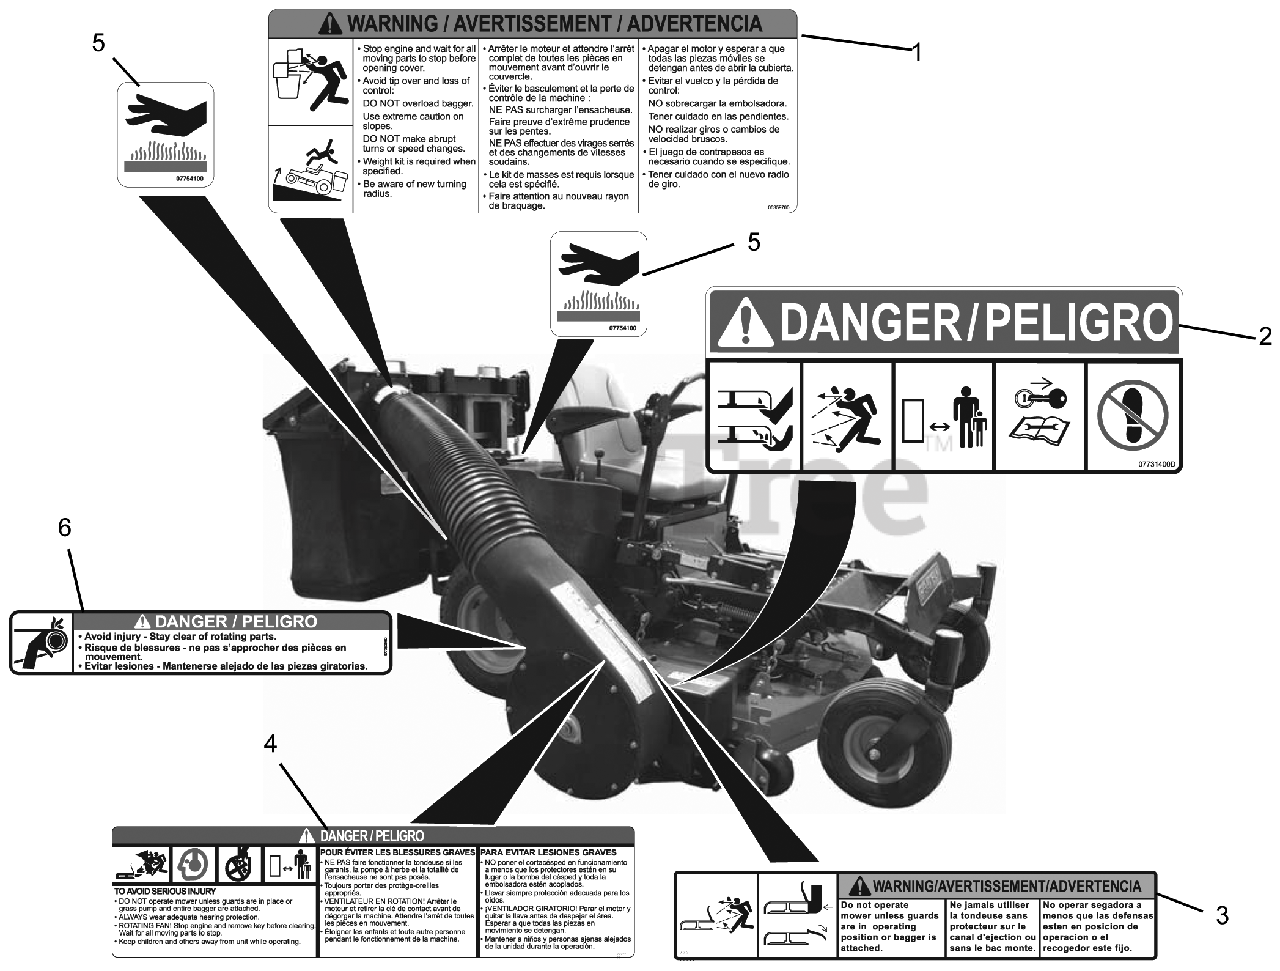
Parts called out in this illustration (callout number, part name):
1	DECAL, BAGGER COVER
2	DECAL, MOWER PAN DANGER
3	DECAL, WARNING
4	DECAL-CAUTION, GRASS PUMP
5	DECAL, HOT SURFACE
6	DECAL- DANGER
